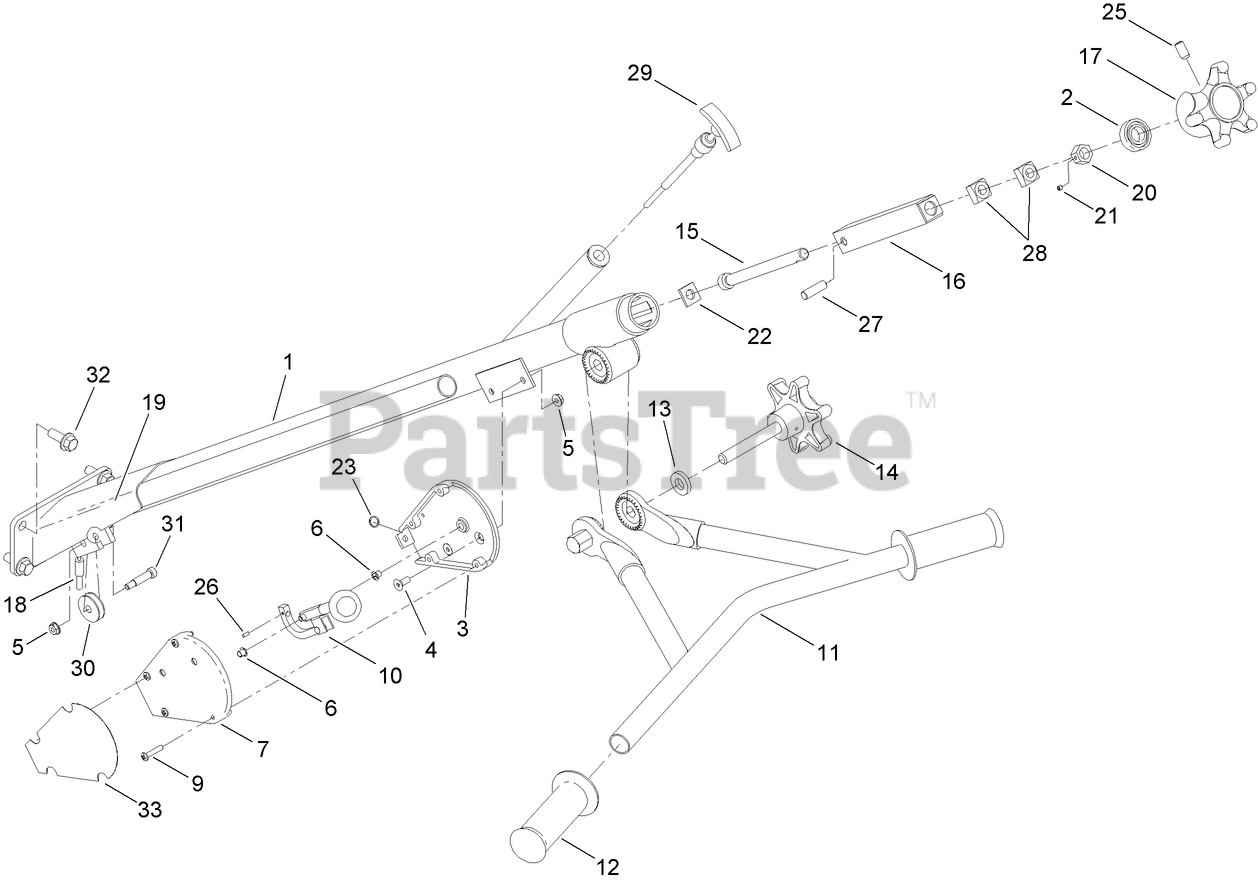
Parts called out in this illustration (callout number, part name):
1	HANDLE-MAIN
2	BEARING-BALL
3	HOUSING-CLUTCH, DYNA
4	SCREW-HSFH
5	NUT-KEPS
6	BUSHING-FLANGE
7	COVER-CLUTCH
9	SCREW-PPH
10	LEVER DYNA ASM
11	HANDLE-ADJUSTMENT
12	GRIP-HANDLE
13	WASHER-FLAT
14	KNOB-ADJUSTMENT
15	ROD-TILT
16	BLOCK-TILT
17	HANDLE-TILT, BLADE
18	CABLE-TILT
19	CLUTCH CABLE ASM
20	NUT-LOCK, TILT
21	SCREW-HSH, SET
22	WASHER-SQUARE
23	RING-EXTERNAL
25	SCREW-HSH, SET
28	NUT-SQUARE
29	CABLE ASM
30	PULLEY-PIVOT
31	SCREW-HSBH
32	SCREW-HHF
33	DECAL-DYNA CLUTCH
